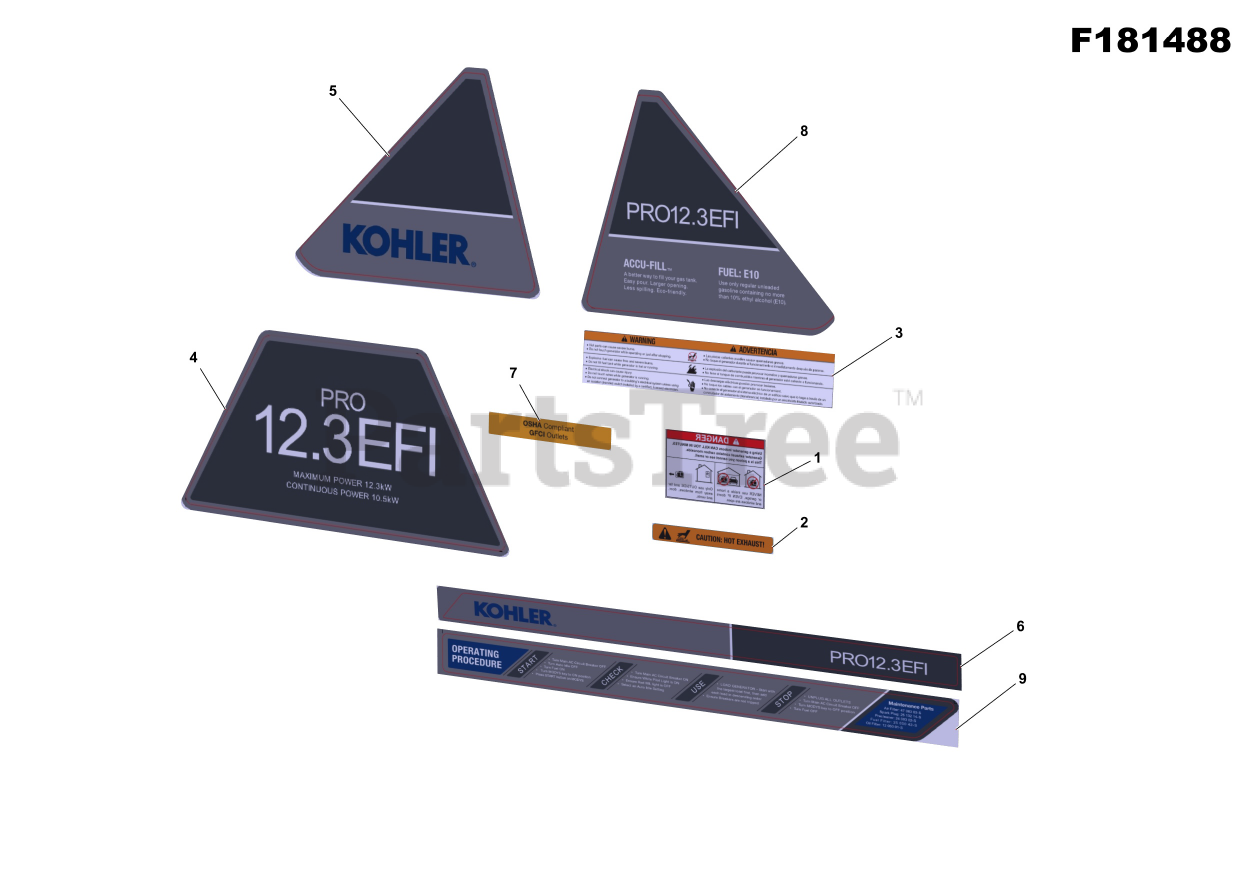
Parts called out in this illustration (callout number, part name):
1	CPSC Decal
2	Hot Exhaust Decal
3	Warning Decal
4	Sticker logo PRO12.3 EFI back
5	Sticker logo PRO12.3EFI left front
6	Sticker logo PRO12.3 left side
7	OSHA Sticker
8	Sticker logo PRO12.3EFI right front
9	Sticker logo PRO12.3 starting procedures
